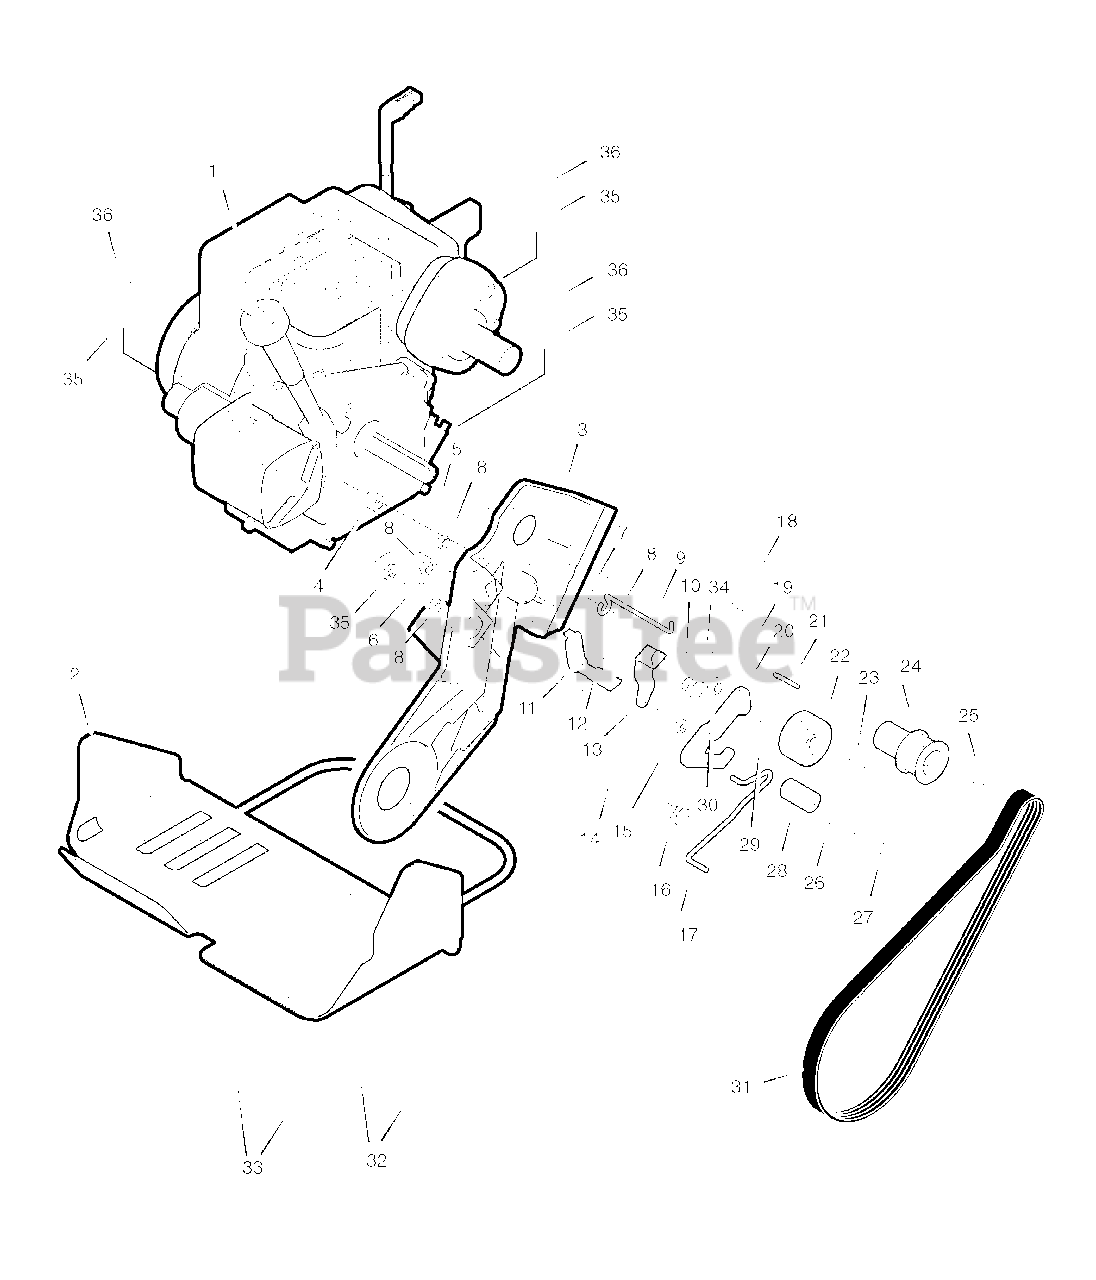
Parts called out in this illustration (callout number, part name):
1	ENGINE, 5HP 4CY B&S *
2	CRADLE ASSEMBLY, Engine
3	FRAME, L.H.
4	ANTIVIBRATION MOUNT, Engine
5	BOLT, Hex 5/16-18 x 0865
6	BOLT, Hex 5/16-24 x 1.125
7	WASHER, Flat
8	LOCKNUT, Hex Center 5/16-18
9	GUIDE, Belt
10	BOLT, Hex Head Shank 5/16-1/2 x 11/64
11	PAD, Brake
12	SCREW, 1/4-20 x 5/8
13	IDLER, Arm Pivot
14	SPRING, Extension .38 O.D. x .039W
15	NUT, Hex 1/4-20
16	BOLT, Hex Head Shank 5/16-1/2 x 11/64
17	WIRE, Brake
18	SPRING, Extension 3/4 O.D. X .069
19	PIN, Cotter
20	ARM, Idler
21	ROD, Clutch Linkage
22	PULLEY, Idler
23	SCREW, 3/8-16 x 1.50
24	PULLEY, Model 9 Engine
25	BOLT, Engine Pulley
26	WASHER, Flat 9/32 x 5/8 x .065
27	SCREW, 1/4-20 x 2.00
28	PINCH ROLLER
29	WASHER, Flat
30	NUT, Hex Head 3/8-16 Control Lock
31	BELT, Drive
32	BOLT, Hex 5/16-18
33	SCREW 3/8-16 x 1.00
34	WASHER, Flat
35	LOCKWASHER, Split
36	NUT, 5/16-18
